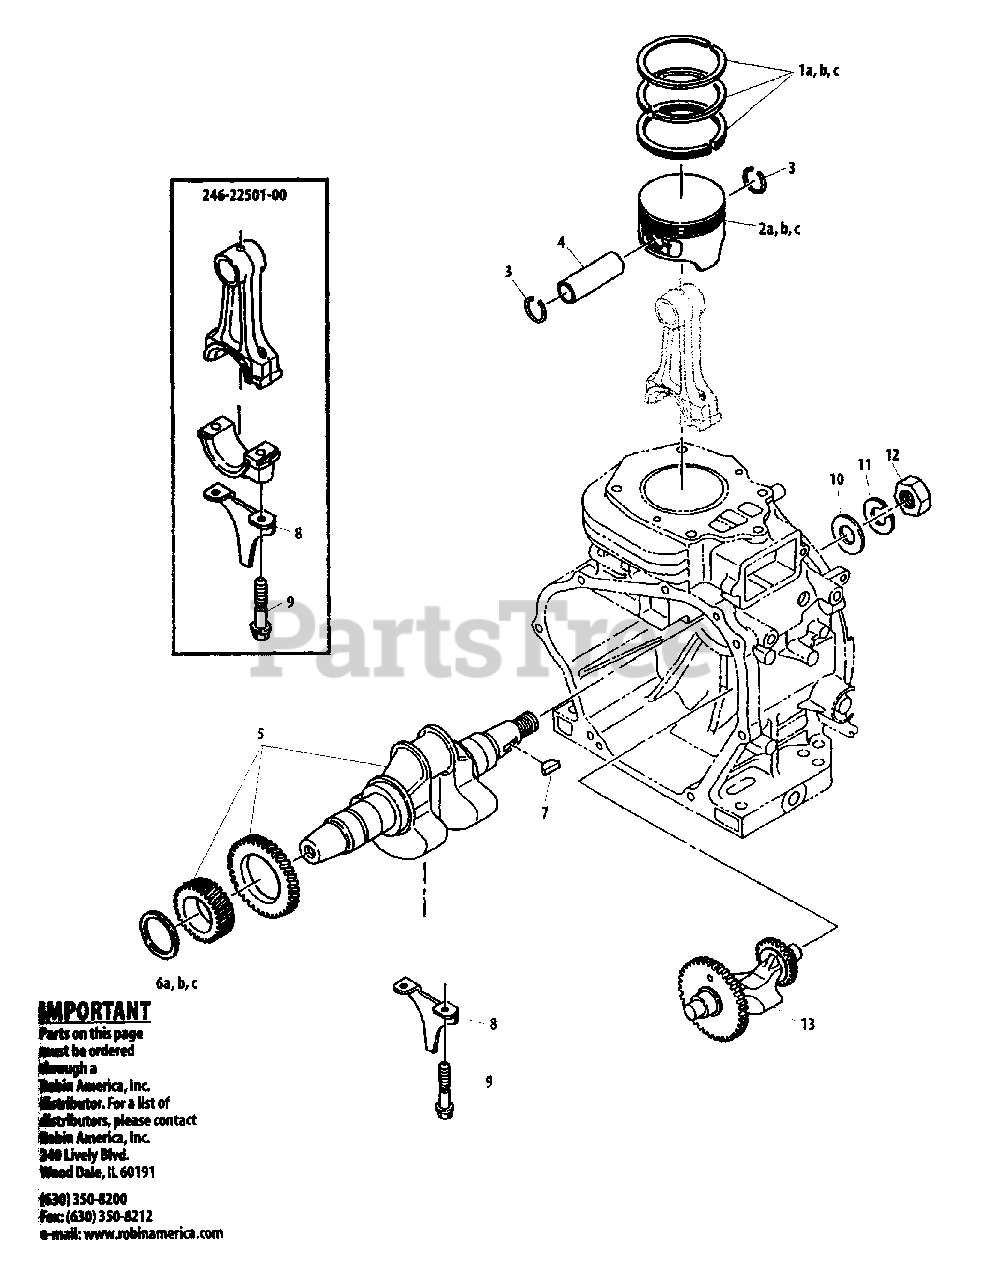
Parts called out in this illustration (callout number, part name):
1A	PISTON RING SET
1B	PISTON RING SET (0.25 MM)
1C	PISTON RING SET (0.50 MM)
2A	PISTON
2B	PISTON (0.25 MM)
2C	PISTON (0.50 MM)
3	RING, RETAINING
4	PIN, PISTON
5	CRANKSHAFT ASSY
6A	SPACER (0.6 MM)
6B	SPACER (0.8 MM)
6C	SPACER (1.0 MM)
8	OIL SCRAPER
9	BOLT
10	WASHER
11	LOCKWASHER
12	NUT
13	SHAFT, BALANCER
